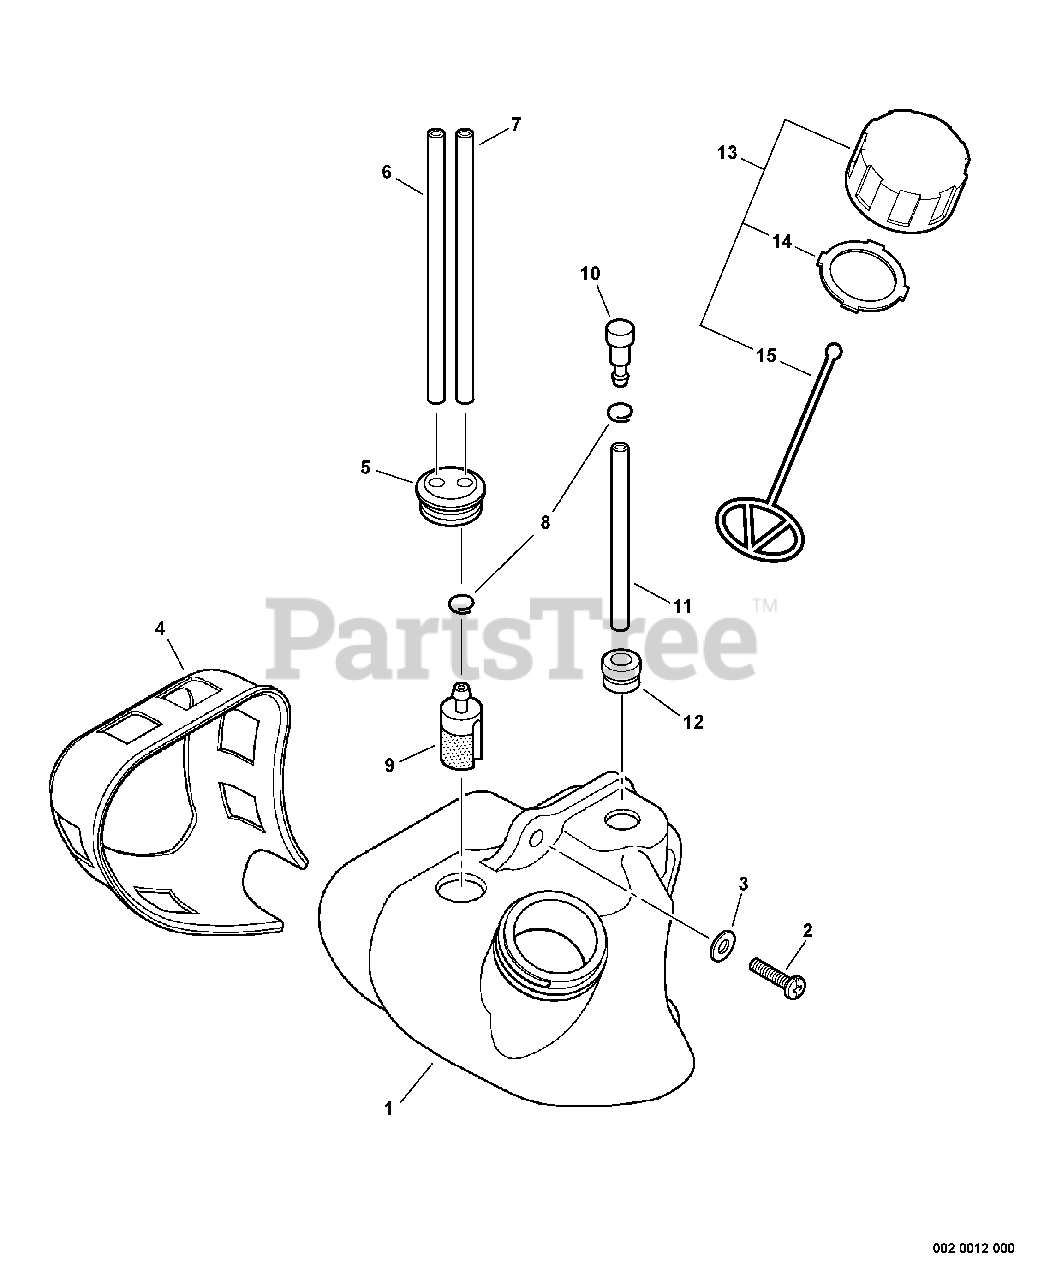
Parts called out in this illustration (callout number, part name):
1	TANK, FUEL
2	SCREW - 5X20 -- TAPPING
3	WASHER - 5
4	GUARD, FUEL TANK
5	GROMMET
6	PIPE - 3X6X85 -- CLEAR
7	PIPE - 3X5X175 -- BLACK
8	CLIP - 6
9	FILTER, FUEL
10	VENT, FUEL TANK
11	PIPE - 3X5X50 -- BLACK
12	GROMMET
13	CAP ASSY - ORANGE
14	GASKET, CAP
15	CONNECTOR, CAP
